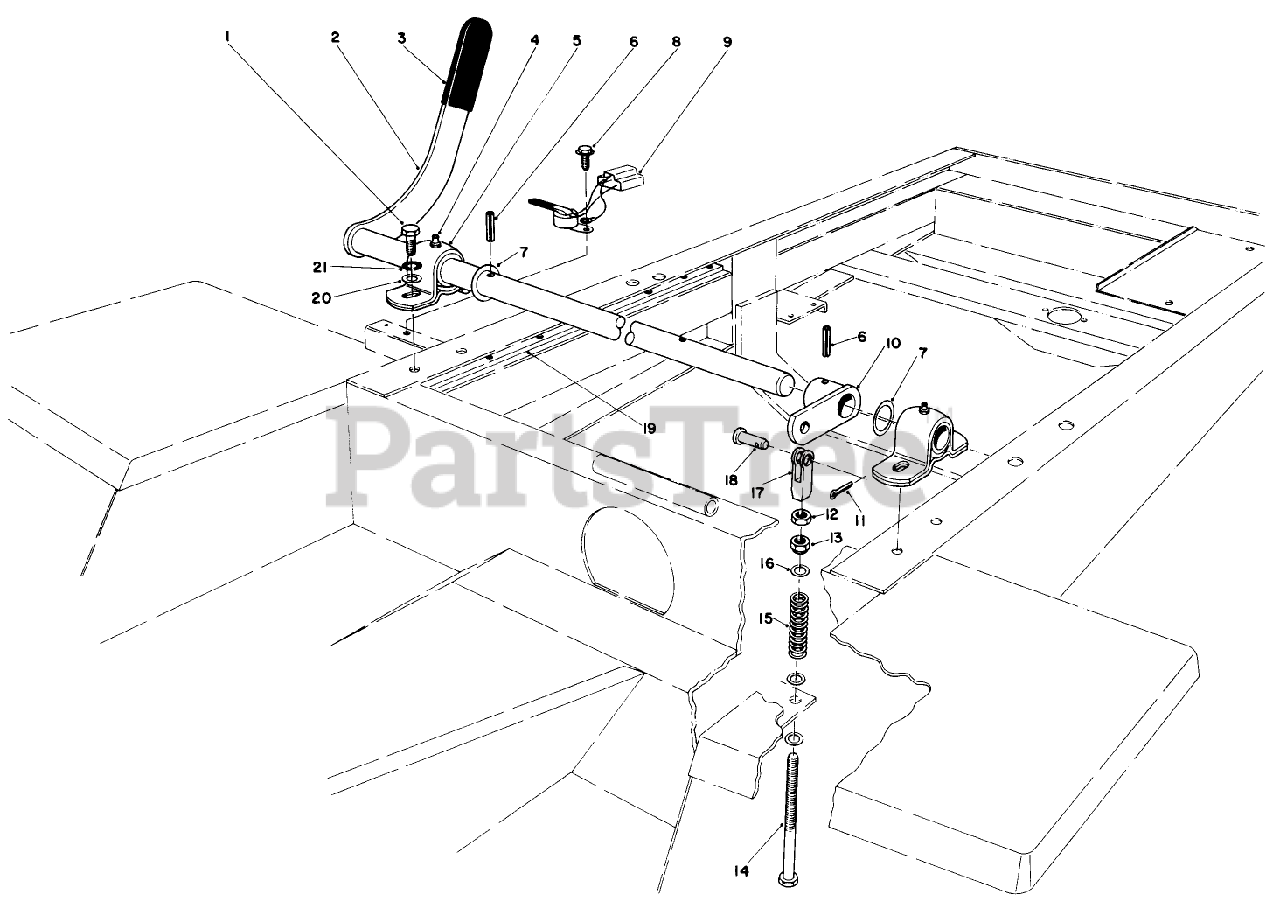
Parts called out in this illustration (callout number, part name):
1	SCREW-HH
2	P.T.0. Lever
3	GRIP-HANDLE
4	FITTING-GREASE
5	BEARING
6	PIN-SPRING
7	THRUST WASHER
8	SCREW-THD FRM,HWH
9	PTO SWITCH
10	ENGAGE ARM WA
11	PIN-COTTER
12	SCREW-CARR
13	NUT-HEX
14	SCREW-ADJUSTING
15	SPRING-COMPRESSION
16	WASHER
17	Yoke
18	PIN-CLEVIS
19	Bar Frame Rail
20	WASHER-FLAT
21	WASHER-LOCK
